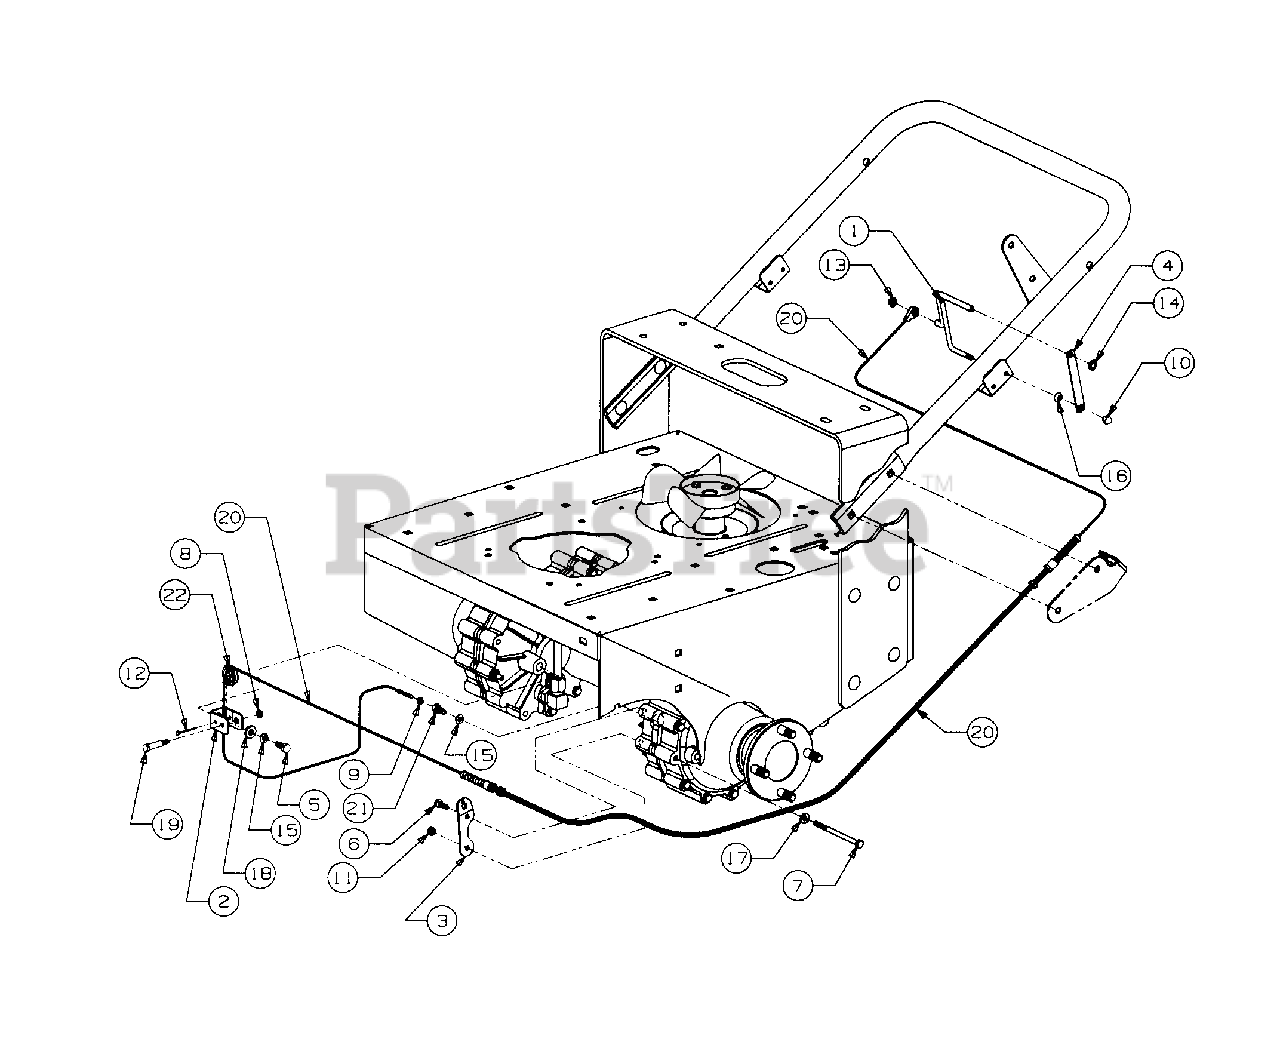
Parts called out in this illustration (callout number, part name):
1	Lever, Drive Wheel Release
2	Bracket, Pulley Mtg
3	Plate, Release Cable Mtg
4	Plate, Retainer
5	Screw, Hex Cap, 5/16-24 X .75 Lg GR5
6	Screw, Hex Wash Hd-Tapp, 1/4-20 X .75 Lg
7	Screw, Hex Cap, 1/4-20 X 4.0 Lg
8	Nut, Hex Top Lock, 1/4-20
9	Nut, Hex, #10-32
10	Nut, Hex Lock Stop, 1/4-28
11	Nut, Hex Top Lock, 1/4-20 GR5
12	Pin, Cotter, 5/32 Dia X 1.25 Lg
13	Nut, Cap Speed, .312 Stud
14	Nut, Push-On Speed, 5/16
15	Washer, Lock, 5/16
16	Washer, Spring
17	Washer, Flat, .25 X .62
18	Washer, Flat, .312 X .750 X .119 Thk
19	Bolt, Pulley
20	Cable, Drive Wheel Release
21	Bolt, Cable Adapter
22	Pulley, Cable
